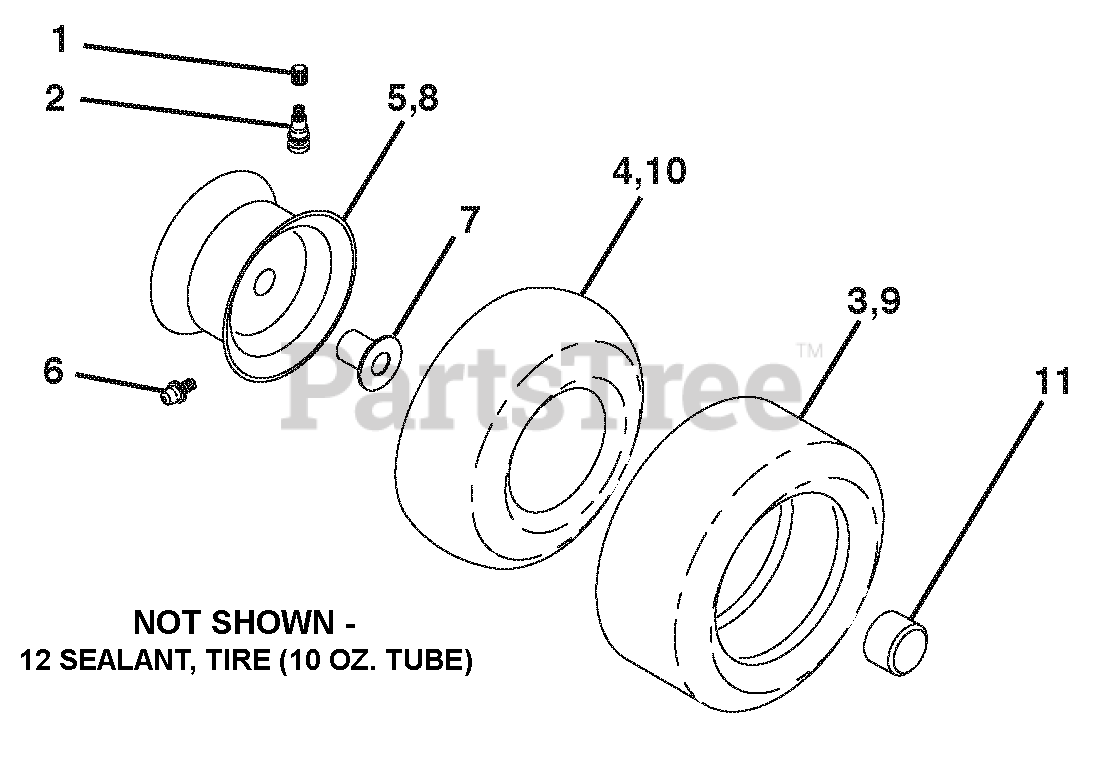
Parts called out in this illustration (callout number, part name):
1	CAP.VALVE.TIRE
2	STEM.VALVE
3	TIRE.F.TS.15 X 6.0 - 6.SERVICE
4	TUBE.INNER.FRONT.#35060
5	RIM ASM.6"FRONT.BLACK.SERVICE
6	FITTING.GREASE
7	BEARING.FLANGE
8	RIM ASM.8"REAR.W.GRY.SRVCE.643
9	TIRE.R.TS-LT.18X9.5-8.C.SERV.
10	TUBE.REAR.9.5 X 8.SERVICE
11	CAP.HUB.AXLE.BLK.1.50 X 1.00
